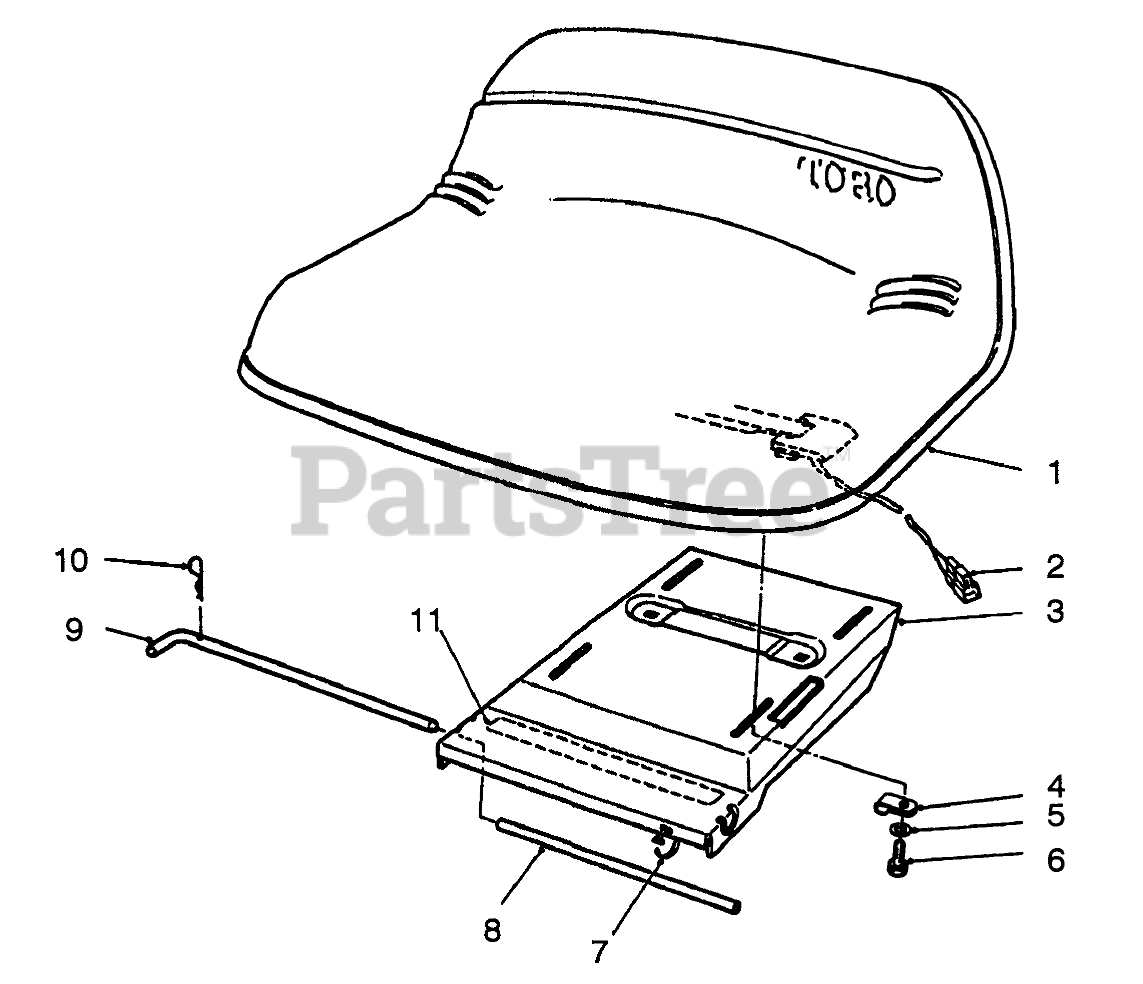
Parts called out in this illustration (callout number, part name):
1	Seat
2	SWITCH-SEAT
3	Base-Seat
4	CLAMP
5	WASHER-PLAIN
6	SCREW-HH
7	TIE-CABLE
8	TUBE-SEAT
9	ROD-SEAT BASE
10	PIN-COTTER
11	DECAL
